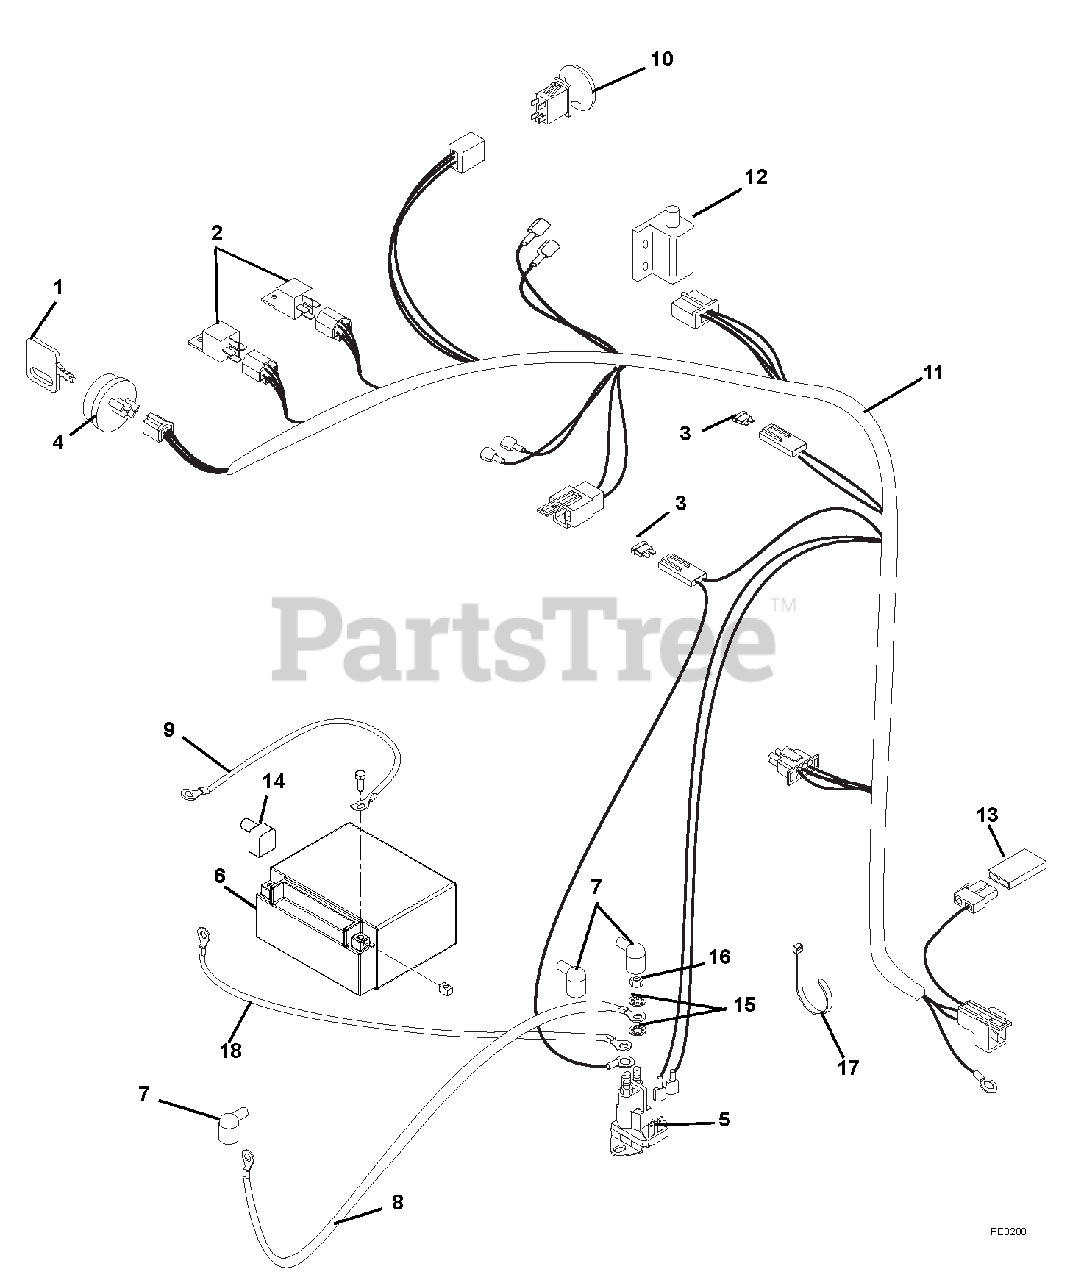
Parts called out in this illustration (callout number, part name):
1	KEY -W/CAP
2	RELAY
3	FUSE-25 AMP ATC TYPE
4	KEY SWITCH
5	SOLENOID, HP RTV
6	BATTERY, 12 VOLT SEALED AGM
7	BOOT, EYELET TERMINAL
8	STARTER CABLE
9	GROUND CABLE
10	SWITCH, CLUTCH
11	HARNESS, ZTXL/ZOOMXL
12	SWITCH- DOUBLE POLE N.O./N.O.
13	DIODE, CONNECTOR SHELL
14	INSULATOR
15	WSHR-LOCK INT .31 YWZC
16	NUT-JAM .31-24 YWZC
17	CABLE TIE LG 5-1/2
18	POSITIVE CABLE
19	HARNESS,MINI-Z HEADLIGHT
